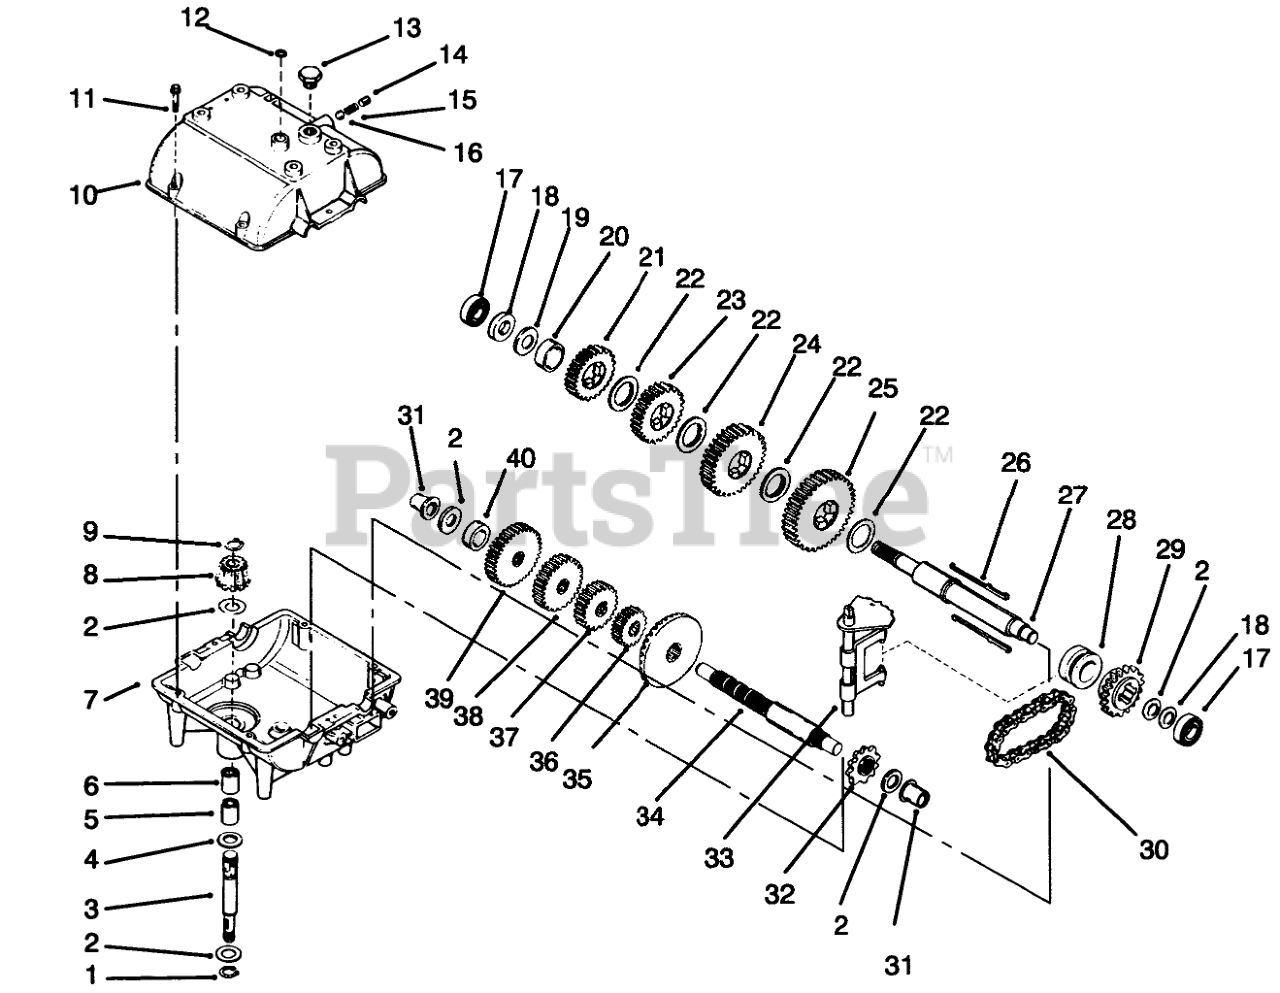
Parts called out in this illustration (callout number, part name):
1	Ring-Snap
2	Washer
3	Shaft-Input
4	O Ring
5	Bearing-Needle
6	Bearing-Needle
7	Case-Transmission
8	Bevel Pinion-Input
9	Ring-Retainer
10	Cover-Transmission
11	Ring Set (.020 O S)
12	Cut Seal-Square
14	Screw-Set
15	Spring
16	Ball-Steel
17	Bearing-Ball
18	Thrust Washer
19	Washer
20	Spacer
21	Gear-Spur, 25 Teeth
22	Washer
23	Gear-Spur 27 Teeth
24	Gear-Spur, 30 Teeth
25	Gear-Spur, 35 Teeth
27	Shaft-Output/Brake
28	Collar-Shift
29	Sprocket-18 Teeth
30	Chain-Roller #41
31	Bushing-Flange
32	Sprocket-9 Teeth
33	Rod and Fork ASM
34	Countershaft
35	Gear-Bevel, 42 teeth
36	Gear-Spur 15 Teeth
37	Gear-Spur, 20 Teeth
38	Gear-Spur 23 Teeth
39	Gear-Spur, 25 Teeth
